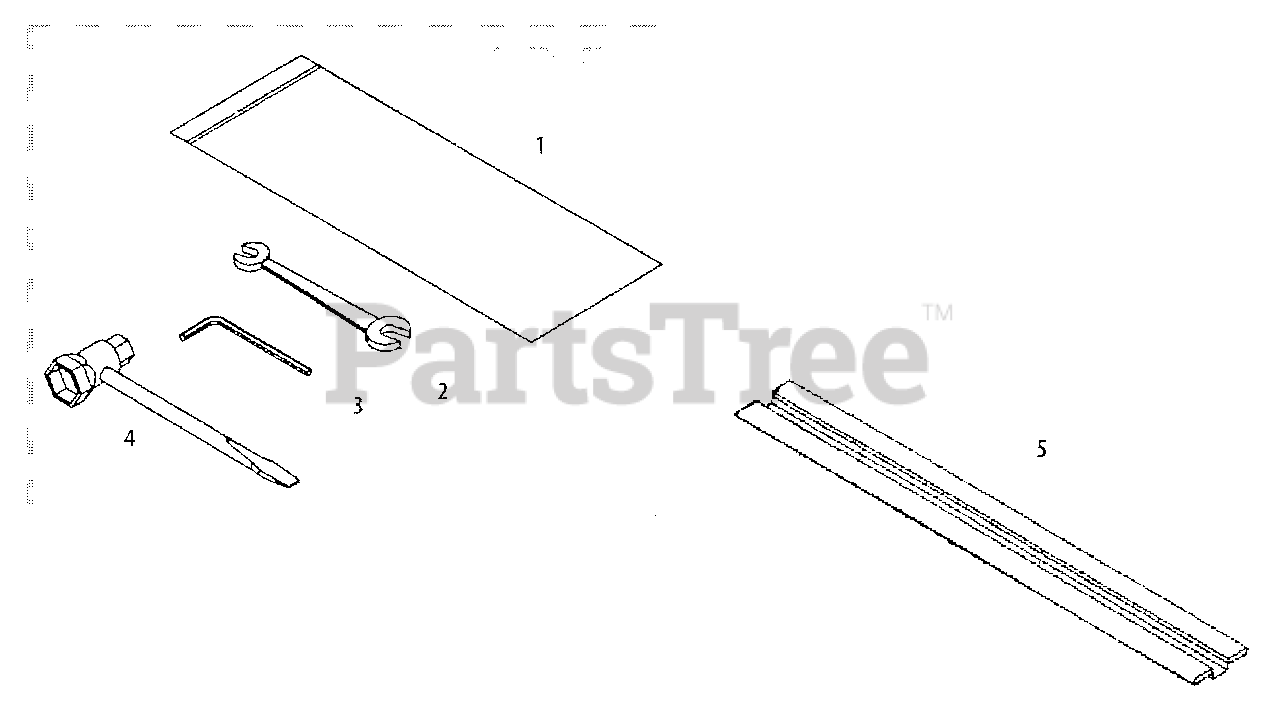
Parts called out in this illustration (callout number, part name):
1	BAG, TOOL
2	SPANNER 8×10
3	WRENCH, ALLEN 4 MM
4	T-WRENCH
5	SCABBARD
65000-92010	SERVICE TOOL KIT
